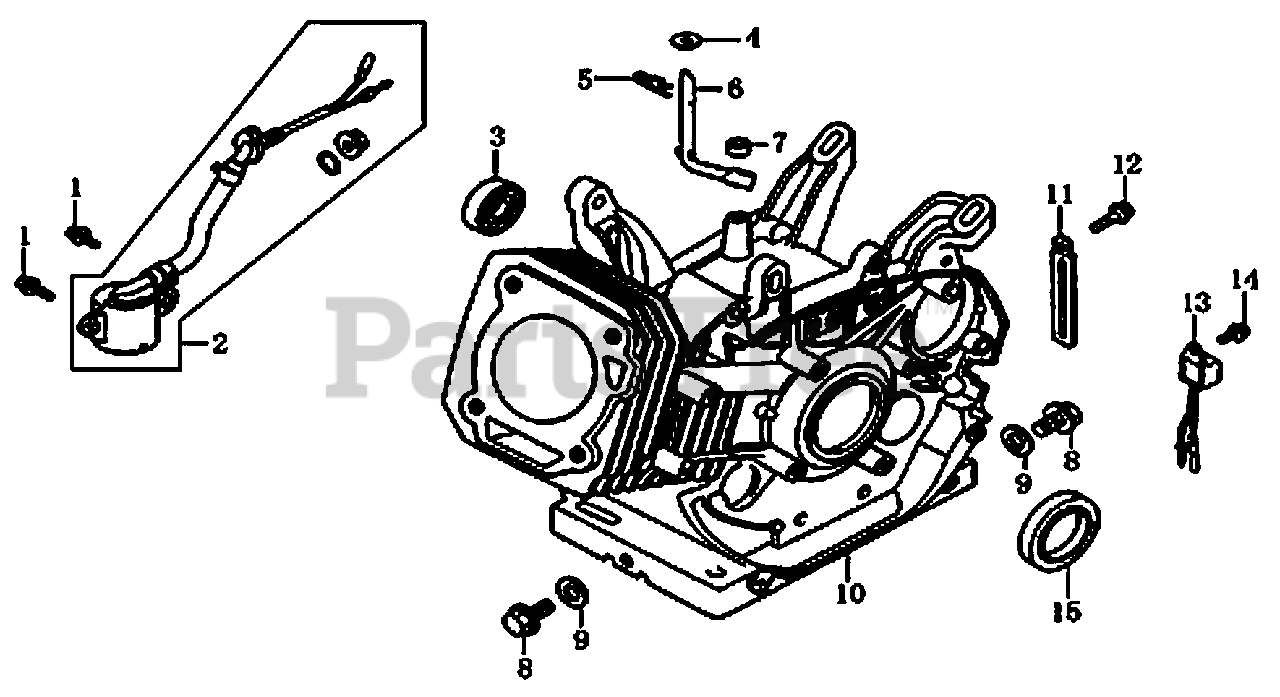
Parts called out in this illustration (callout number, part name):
1	BOLT, FLANGE, 6×14
2	SWITCH ASSY., OIL LEVEL
3	BEARING, RADIAL BALL, 6202
4	WASHER,8x16x1.2
5	PIN, LOCK, 10MM
6	SHAFT, GOVERNOR ARM
7	OIL SEAL, 8×14×4
8	BOLT, DRAIN PLUG
10	CRANKCASE
12	BOLT, FLANGE, 6×12
13	ALERT UNIT,OIL
14	BOLT, FLANGE, 6×12
15	SEAL, OIL
